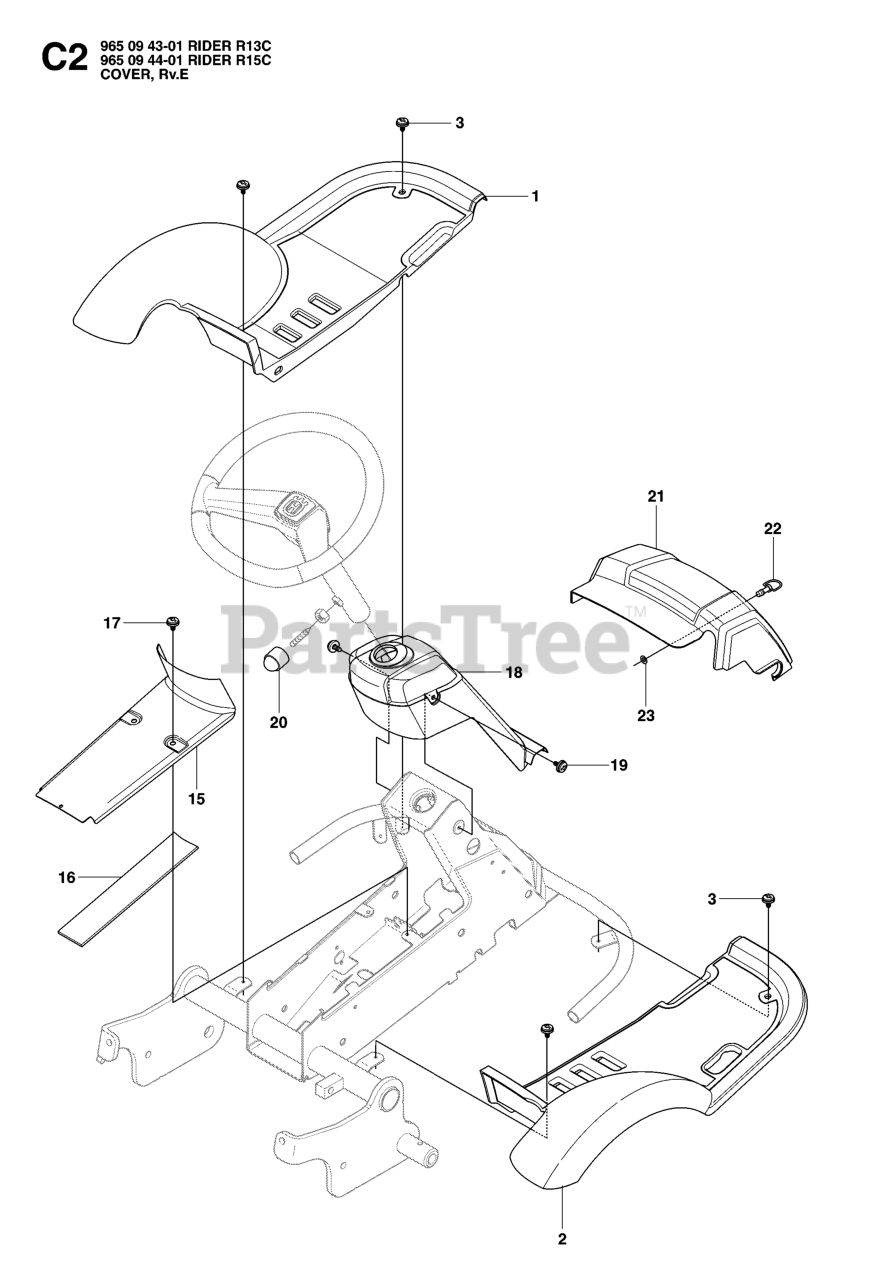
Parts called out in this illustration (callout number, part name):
1	FOOT PLATE
2	FOOT PLATE
20	PROTECTIVE COVER
22	BOLT
